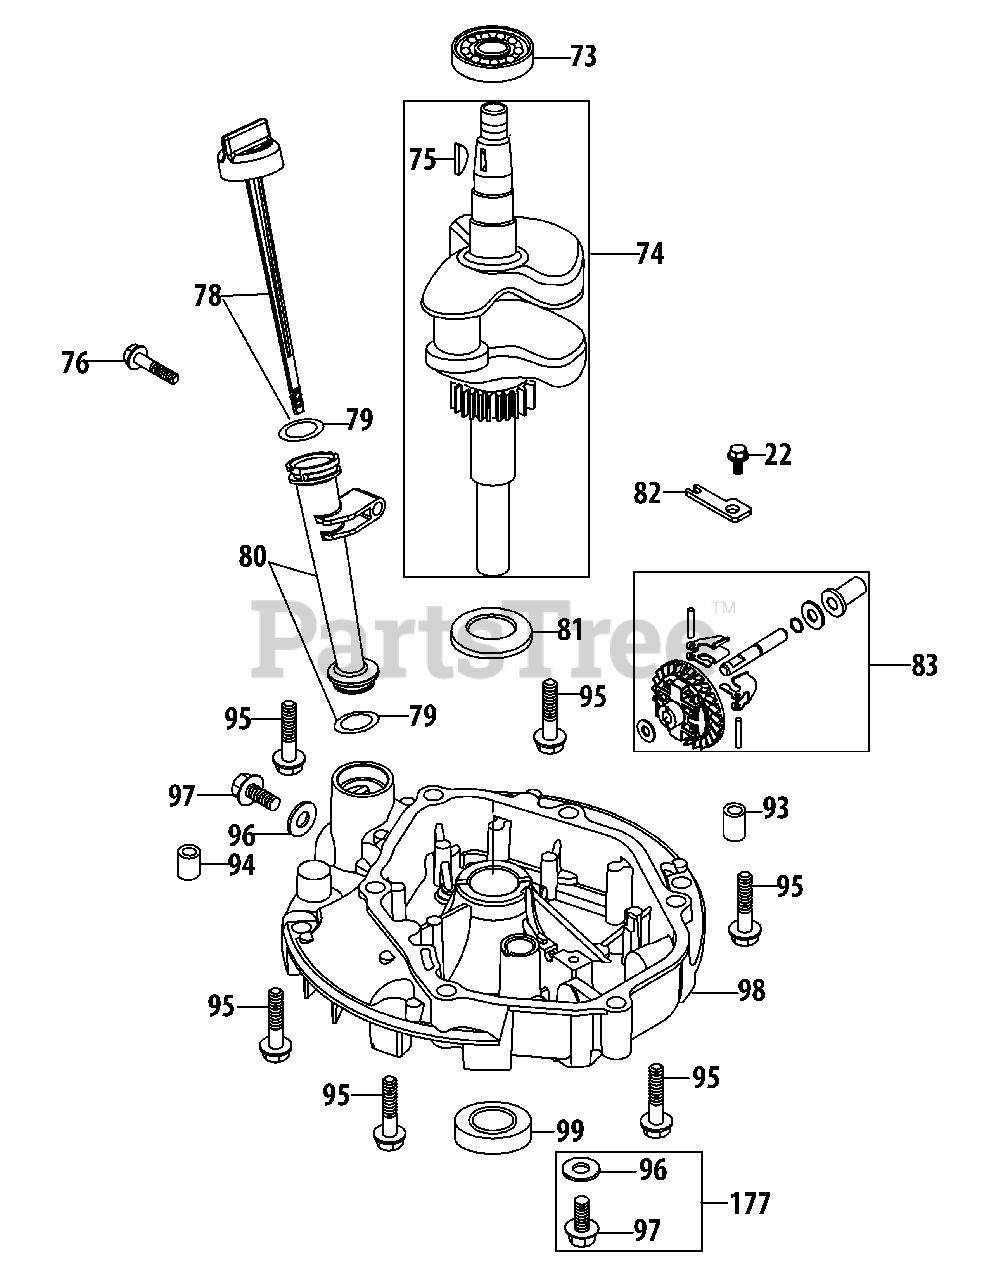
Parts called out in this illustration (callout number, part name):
22	Bolt M6×14
73	Main Bearing
74	Crankshaft Assembly
75	Woodruff Key
76	Bolt M6×35
78	Dipstick Assembly
79	Dipstick / Fill Tube O-Ring
80	Oil Fill Tube Asm
81	Crankshaft Thrust Washer
82	Governor Gear Mounting Plate
83	Governor Gear/Shaft Assembly
93	Dowel Pin 7×14
94	Dowel Pin 9×14
95	Bolt M8×50
96	Oil Drain Plug Washer
97	Oil Drain Plug
98	Crankcase Cover
99	Lower Crankshaft Seal
177	Oil Drain Plug And Washer Ass'Y
